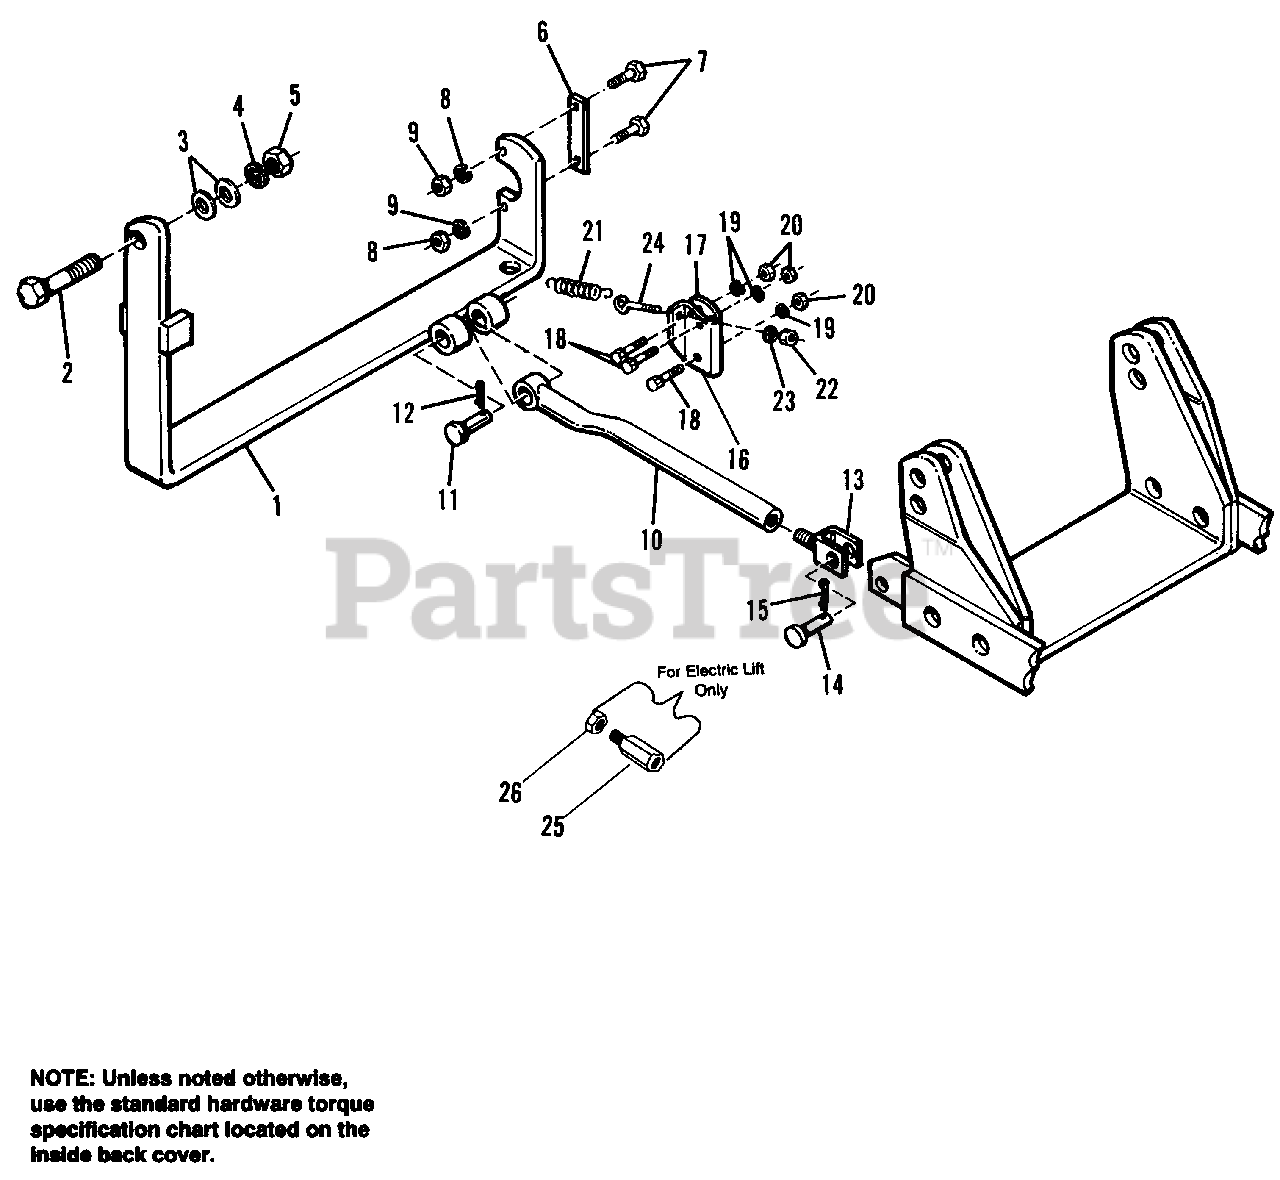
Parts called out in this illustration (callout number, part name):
1	BRACKET, Lifting, Manual
2	CAPSCREW, Hex, 1/2-13 x 1-3/4
3	WASHER, Plain, 1/2
4	LOCKWASHER, 1/2
5	NUT, Hex, 1/2-13
6	PLATE, Anchoring
7	CAPSCREW, Hex, 1/4-20 x 1
8	LOCKWASHER, 1/4
9	NUT, Hex, 1/4-20
11	PIN, Clevis
12	COTTER PIN, 3/32 x 1
13	FORK, Threaded
14	PIN, Clevis, 5/8 x 1-5/8
15	CLIP, Hairpin, 1/8 x 2-9/16
16	BRACKET, Fixation
17	PLATE, Retaining
18	CAPSCREW, Hex, 3/8-16 x 1-1/4
19	LOCI<WASHER, 3/8
20	NUT, Hex, 3/8-16
22	LOCIKWASHER, 1/4
23	NUT, Hex, 1/4-20
24	EYEBOLT, 1/4-20 x 4
25	ROD, Extension (Electric Lift Only)
26	NUT, Hex, 5/8-11 (Electric Lift Only)
